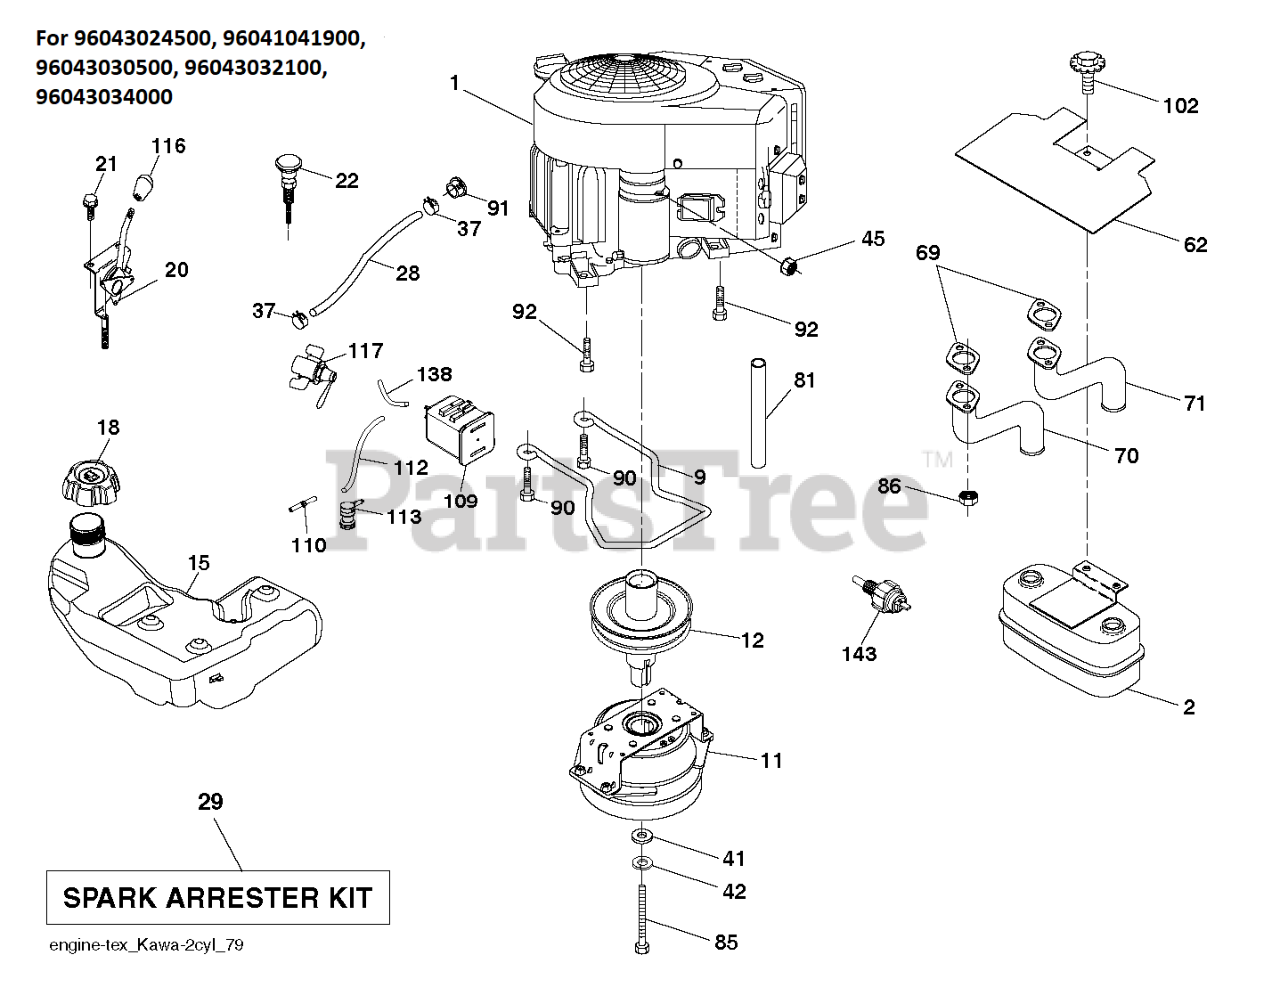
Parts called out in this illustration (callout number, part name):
2	MUFFLER.ASM.TWIN.MNTG.BRACKET
11	CLUTCH.OGURA.5.0PD.GT1.5A-EH01
12	PULLEY ENGINE
15	TANK ASSY W/CAP 4 GAL REAR EPA
15	TANK ASSY W/CAP 4 GAL EPA
15	TANK ASSY W/CAP REAR CARB
18	FUEL CAP
18	CAP ASSY FUEL 3" GRAY
18	Fuel Caps
20	CONTROL.THROTTLE.PRO.
22	CONTROL.CHOKE.ERGO.BLACK
28	HOSE 1/4" LOW PERMEATION FUEL
29	KIT.SPARK ARRESTOR 794945 B&S
37	HOSE CLAMP
45	NUT HEX_LRG FLG_1_4-20_LOCK
45	Hardware
62	SERVICE KIT HEAT SHIELD
70	TUBE.EXHAUST.LH.FR961/FR730
71	TUBE.EXHAUST.RH.FR961/FR730
81	TUBE, DRAIN OIL ASM.
85	BOLT.HEX.7/16-20X3.GR5.YELLOW
86	NUT.HEX.FLANGE.TOPLOCK
90	SCREW 3/8-16X1
91	BUSHING.1.375OD
92	SCREW 3/8-16X1
102	BOLT.HEX.HD.WASHER.5/16-18X.75
109	CANNISTER, CARBON
110	VALVE.ASM.ANTI-SLOSH
112	HOSE 1/4" LOW PERMEATION FUEL
113	VALVES
116	KNOB - SHIFT
117	VALVE FUEL RESERVE
138	PURGE.LINE.36"REAR.CALIFORNIA
138	Hoses
143	SENSOR.SWITCH.PRESSURE.OIL
